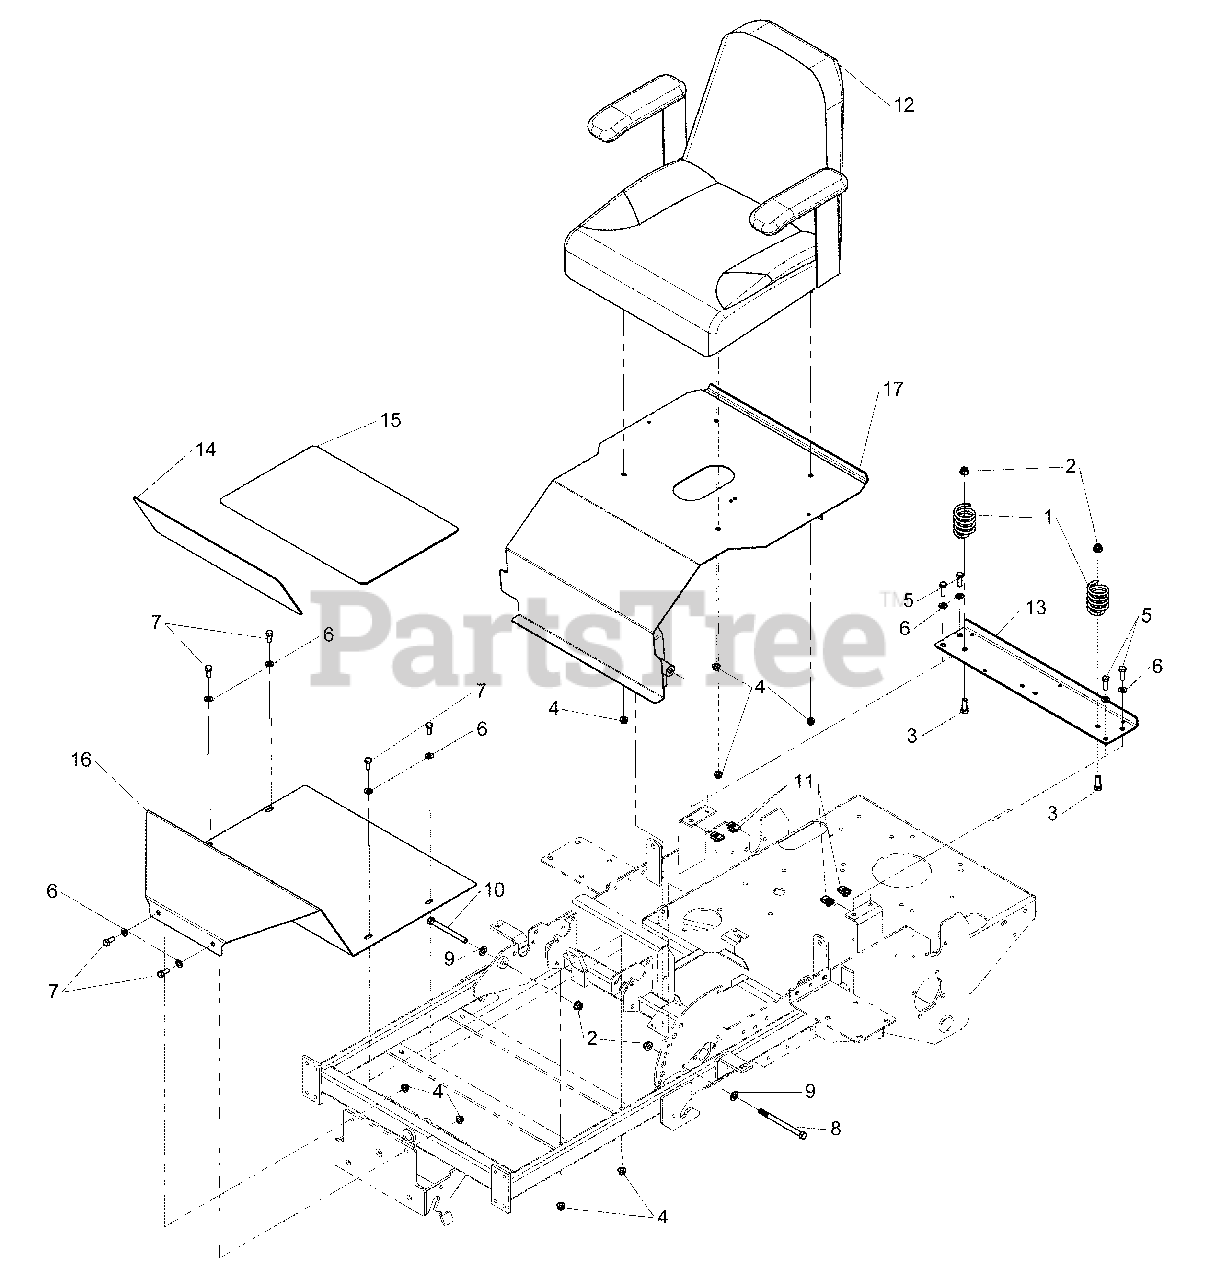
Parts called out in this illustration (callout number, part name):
1	SPRING, CONTROL ROD
2	NUT, 3/8-16 HEX NYLOCK FLANGE
3	BOLT, 3/8-16 X 1" GD5
4	NUT, 5/16-18 HEX NYLOCK FLANGE
5	BOLT, 5/16-18 X 1" GD5
6	WASHER, 5/16" SAE
7	BOLT, 5/16-18 X 3/4" GRD5
8	BOLT, 3/8-16 X 5" GD5
9	WASHER 3/8" SAE
10	BOLT, 3/8-16 X 4" GD5
11	BODY CLIP 5/16-18 X 1/2" DEEP
13	MOUNT, OIL FILTER
14	SAFETY WALK, FLOOR REST
15	SAFETY WALK, FLOOR PLATE
16	PLATE, FLOOR DETAIL
17	WELD, SEAT PLATE
